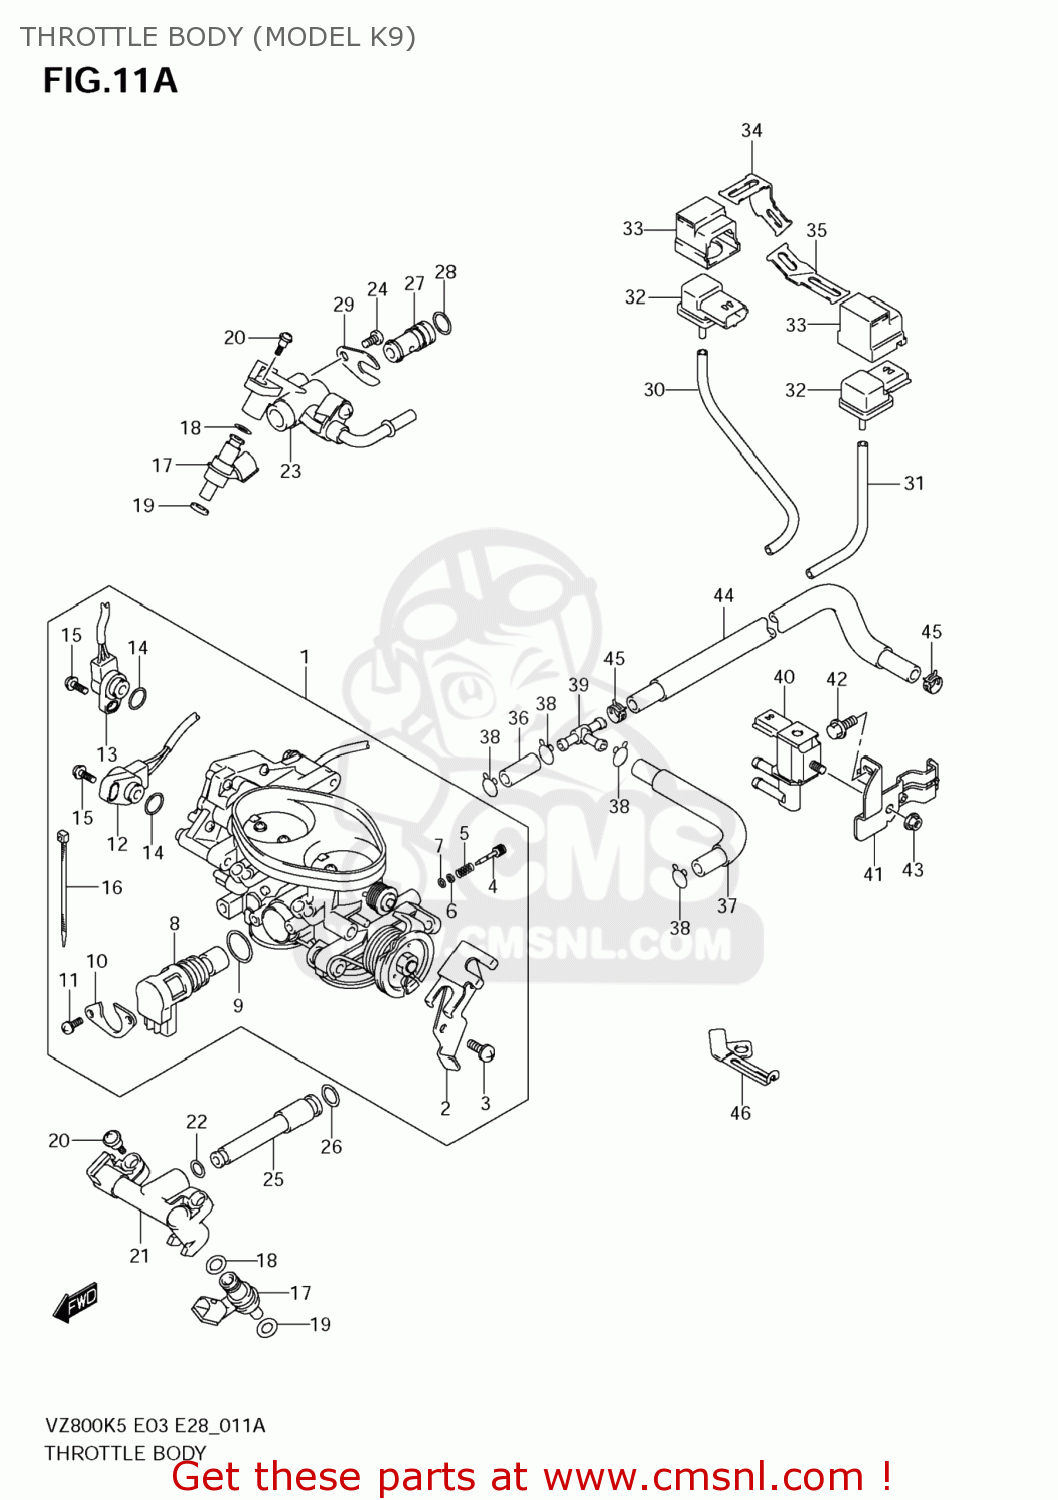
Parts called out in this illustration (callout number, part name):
1	BODY ASSY,THRO
2	PLATE,STAY
3	SCREW
4	SCREW,AIR ADJUST
5	SPRING
6	WASHER
7	O RING
8	VALVE ASSY,ISC
9	O RING
10	PLATE,ISC VALVE
11	SCREW
12	SENSOR ASSY,TH
13	SENSOR ASSY,TH
14	O RING
15	SCREW
16	CLAMP(L:145)
17	INJECTOR ASSY
18	O RING
19	RING,SEAL
20	SCREW,THROTTLE COVER
21	PIPE SET,FUEL FR
22	O RING
23	PIPE SET,FUEL RR
24	SCREW
25	JOINT
26	O RING
27	PLUG,STRAIGHT
28	O RING
29	PLATE,STAY
30	HOSE
31	TUBE,RUBBER
32	SENSOR,PRESSURE
33	HOLDER,SENSOR
34	BRACKET,BOOST SENSOR FR
35	BRACKET,BOOST SENSOR RR
36	HOSE
37	TUBE,RUBBER
38	CLIP
39	NIPPLE
40	VALVE ASSY,DUTY FOR PURGE
41	BRACKET,PURGE VALVE
42	BOLT
43	NUT
44	HOSE,CANISTER PURGE
45	CLIP
46	CLAMP,EVAPORATOR HOSE
